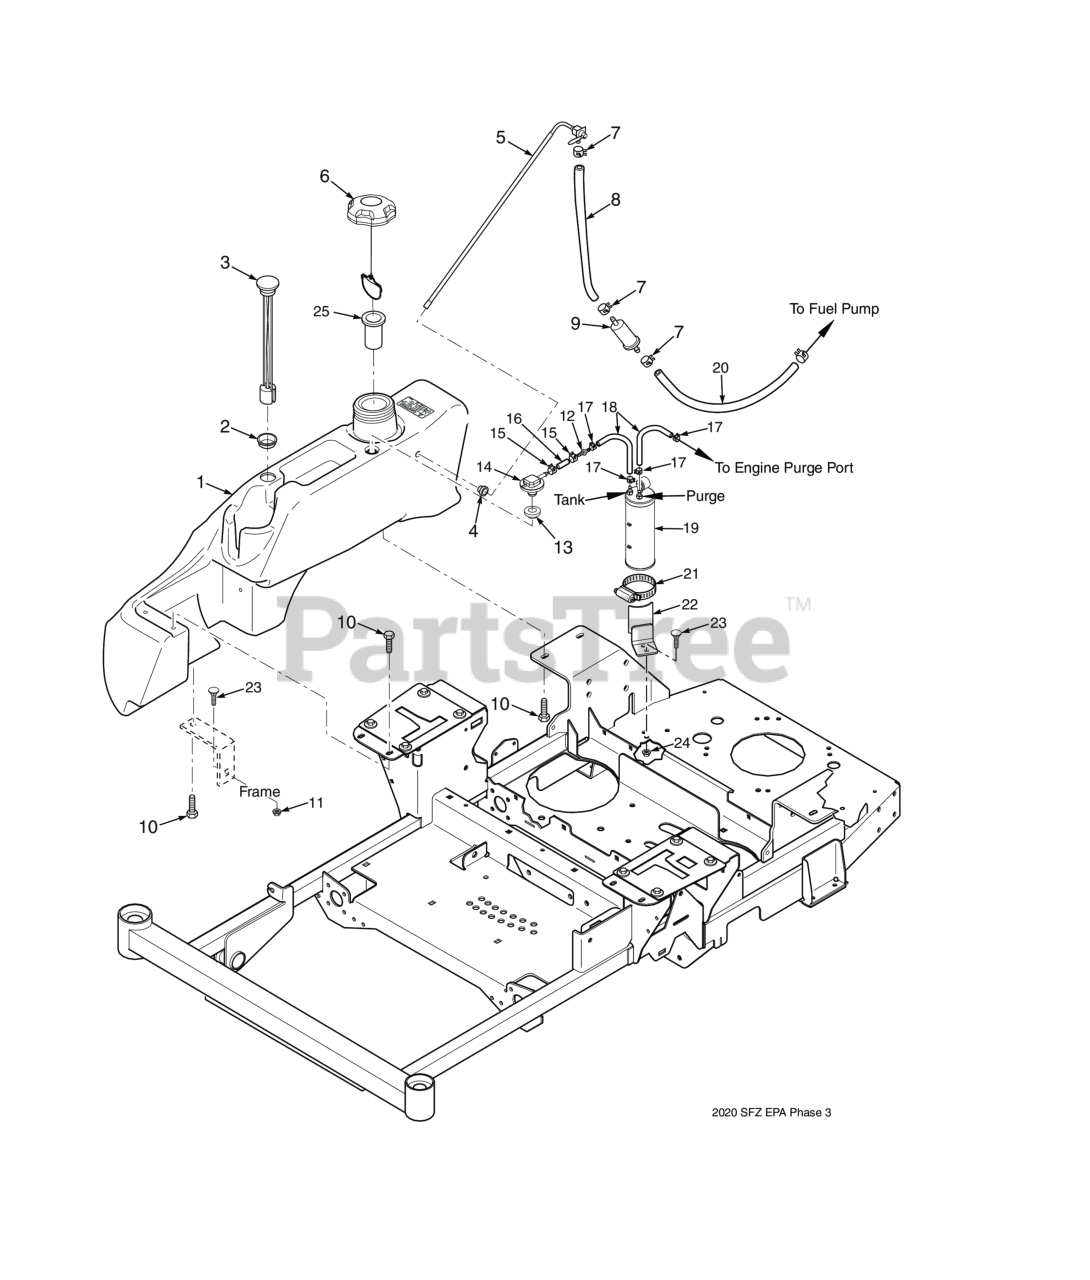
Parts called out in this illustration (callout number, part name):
1	Fuel Tank Assembly - SPZ (Includes 2,3,4,5,13,14)
2	Grommet, Fuel Gauge
3	Fuel Gauge Assembly
4	Bushing, 0.56" Dia. Viton
5	Fuel Tube Assembly
6	Fuel Cap w/ Tether (E.P.A.)
6	Gasket, Fuel Cap
6	Fuel Cap w/Tethered - California Models Only
7	Clamp, Fuel Hose 1/4" Hose I.D.
8	Fuel Hose, 1/4" I.D. Non-Perm (791DFI Fuel Return) - Order by Inch
9	Fuel Filter
10	CAP SCREW, 5/16-18 X 1/2" SERRATED FLANGE HEX
11	Nut, Flange Head Elastic Stop 5/16-18
12	Mender, 1/4 x 3/16 w/0.02 Hole
13	Grommet, Viton,
14	Remote Vent, No Valve
15	CLAMP, FUEL HOSE(KAWASAKI ONLY)
16	Hose, 1/4" Vapor Recovery (order by inch)
17	Clamp, Vapor Recovery Hose 3/16"
18	Hose, Vapor Recovery 3/16" (order by inch)
19	Carbon Canister - SVR-52V / SVR-61V
20	Fuel Hose
21	Clamp, 3-1/2" Max. Dia.
22	Bracket Weldment, Kohler Models
23	Bolt, 5/16-18 x .75 RHSN Carriage
24	Nut, Serrated Flange 5/16-18 (Right Front Engine Mounting, Briggs and Kohler Only)
25	Tube, Fuel Tank Insert - 4"
